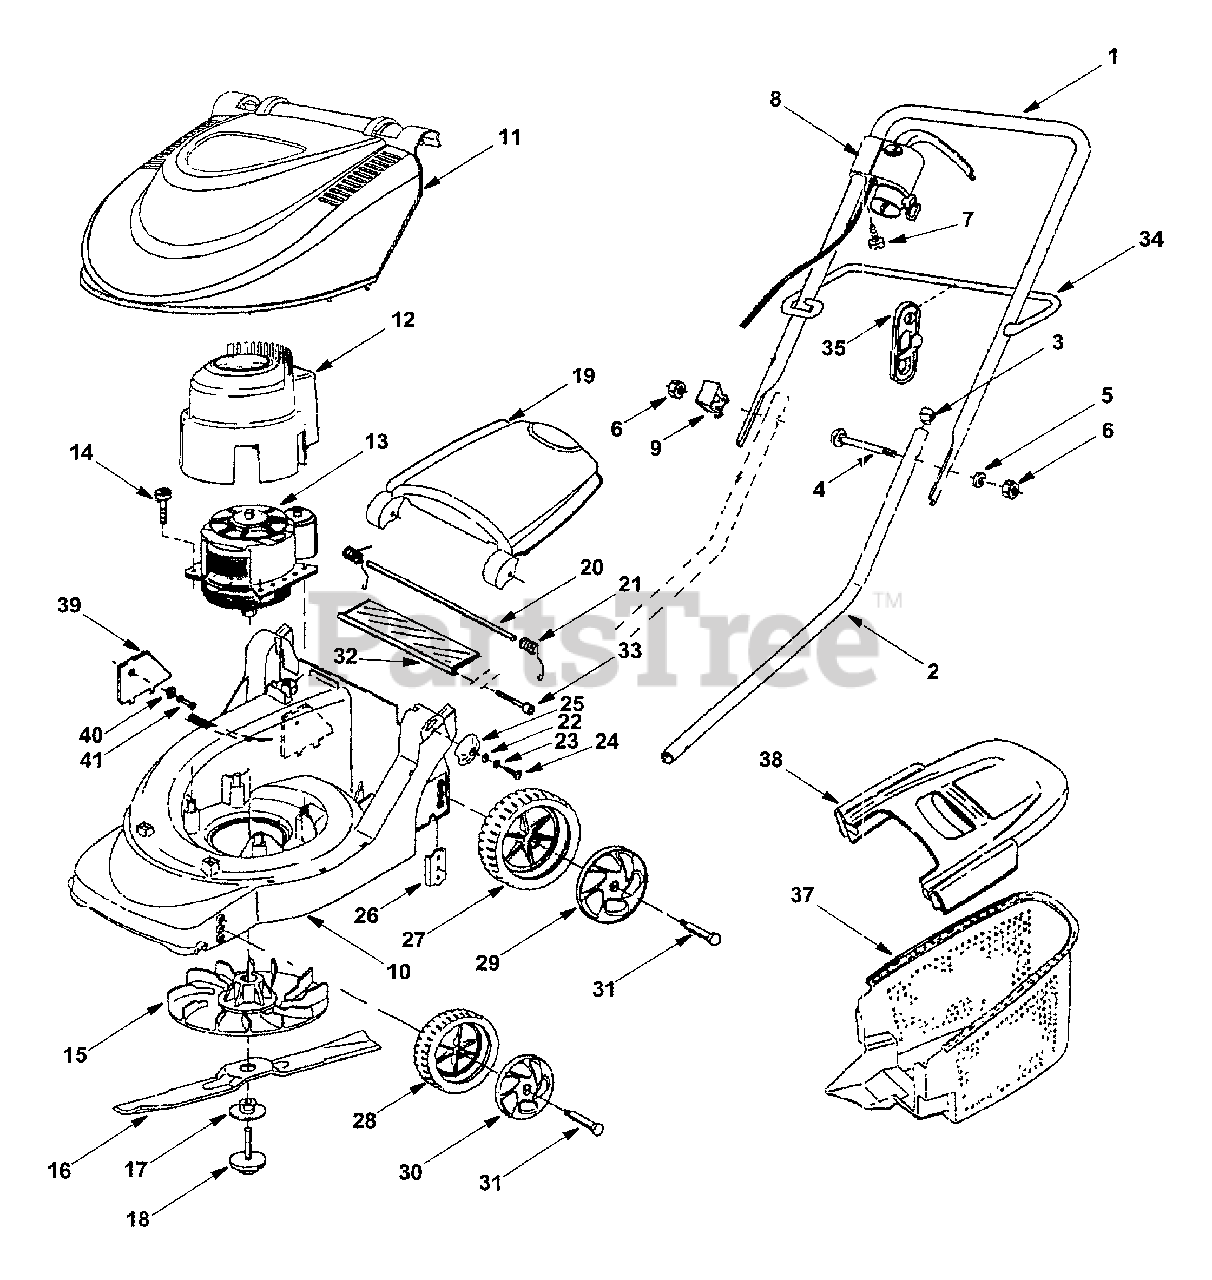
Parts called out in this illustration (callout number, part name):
4	Handle Bolt
5	Lock Washer
6	Hex Nut
7	Screw
8	Motor / Blade Control Switch
9	Cord Insulator
10	Mower Housing
11	Electric Motor Cover
12	Air Guide Pot
13	Electric Motor
14	Screw
15	Blade Hub Assembly
16	Cutting Blade
17	Lock Washer
18	Blade Bolt
19	Rear Discharge Door
21	Spring
22	Washer
23	Lock Washer
24	Screw
26	Holder Plate
27	Rear Wheel
28	Front Wheel
29	Rear Wheel Cap
30	Front Wheel Cap
31	Axle Bolt
32	Rear Trailing Shield
33	Screw
34	Guide Rod
35	Cable Clamp
37	Grass Bag
38	Grass Bag Cover
39	Protection Plate
40	Washer
41	Rivet
